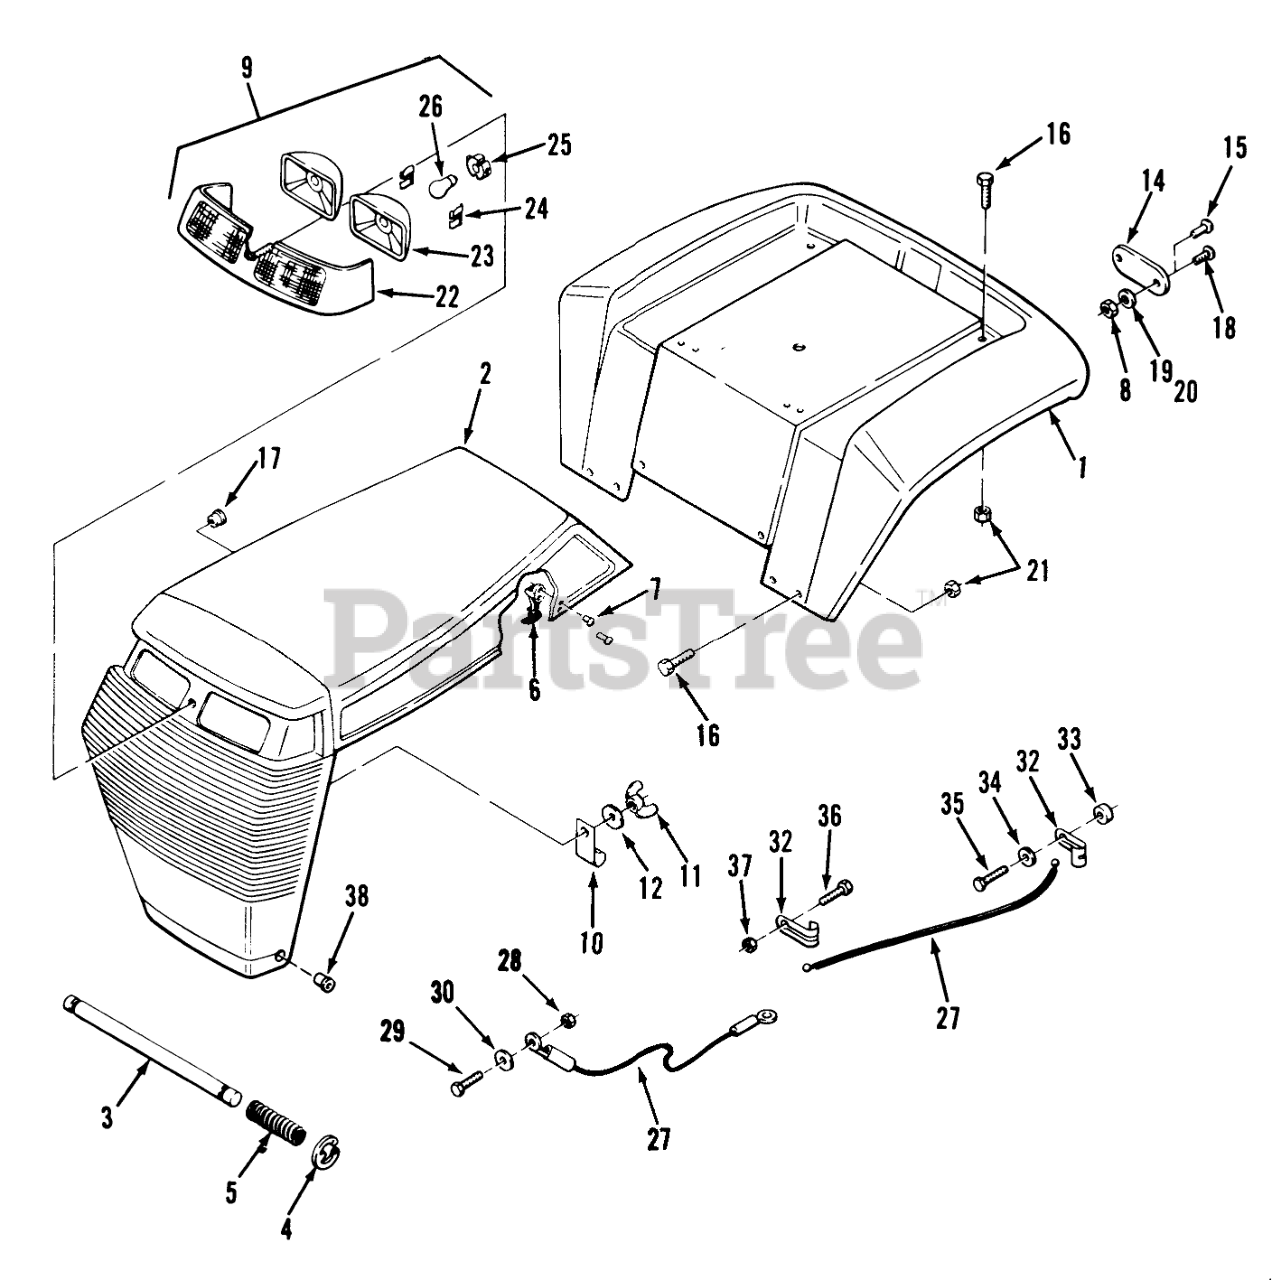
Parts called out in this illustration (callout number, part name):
1	FENDER R
2	Hood & Grill
4	E-Ring
5	SPRING
6	HANDLE ASM
7	RIVET-POP
8	Nut
9	Headlight Bar Assembly (Incl. Ref. #22-24 & 26) (212-5 & 212-H)
10	J-CLIP
11	WING NUT
12	WASHER
14	Reflector
15	Poprivet
16	SCREW-CARR
17	BUSHING-NYLON 1.093
18	Screw
19	WASHER
20	Lockwasher
21	Nut
22	LIGHT-BAR BLACK
23	LIGHT POD
24	RETAINER
25	SOCKET-HEADLIGHT
26	BULB
27	Hood Lanyard Cable
28	Nut
29	Screw-Machine
30	WASHER-BACKING
32	CLEVIS
33	SPACER
34	Washer
35	Bolt
36	Screw-Machine
37	Nut
38	NYLINER BUSHING
